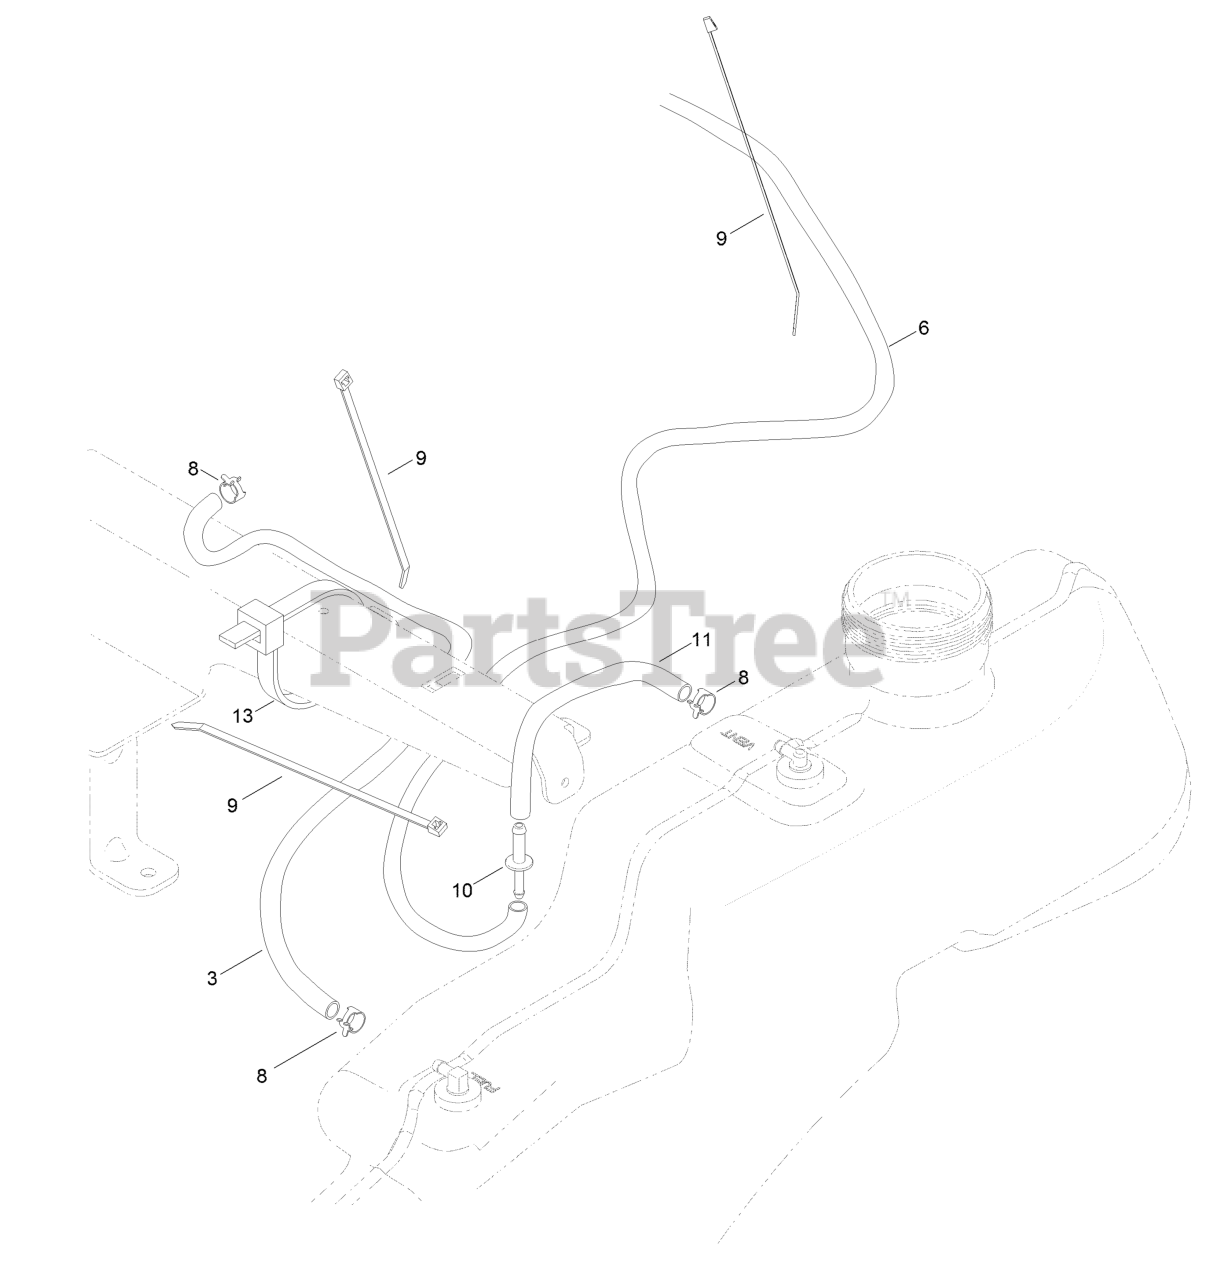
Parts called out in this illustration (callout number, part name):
3	HOSE-FUEL
6	HOSE-FUEL
8	CLAMP-HOSE
9	TIE-CABLE
10	ADAPTOR-ORIFICE
11	HOSE-FUEL
13	TIE-CABLE
